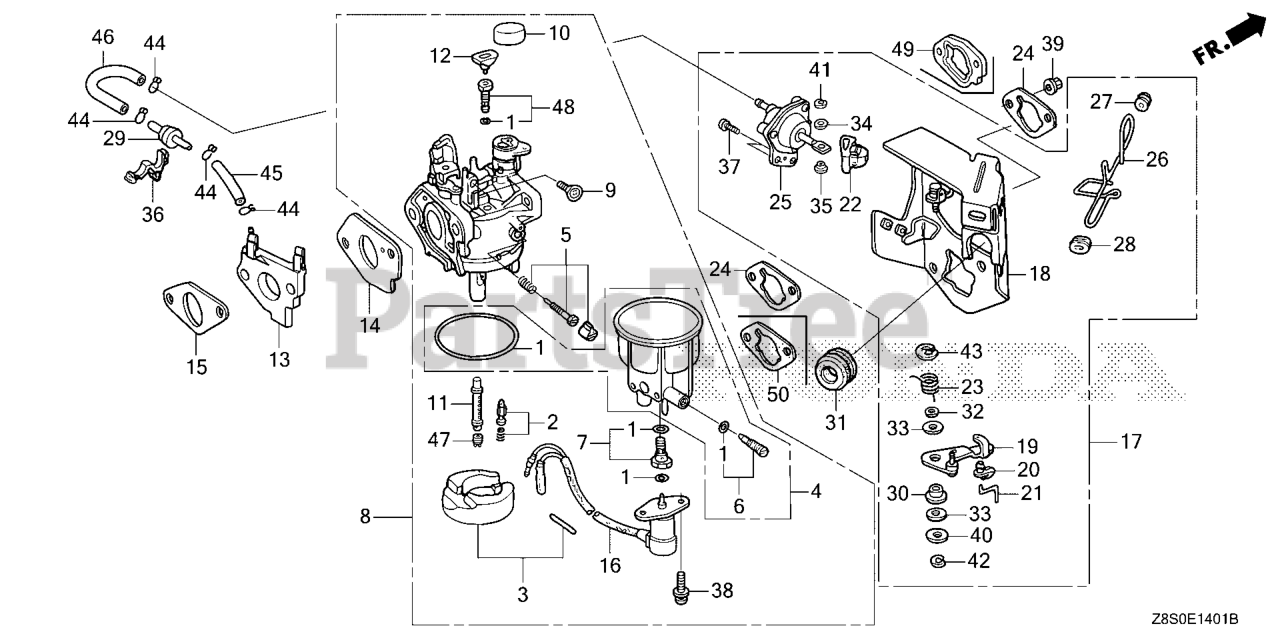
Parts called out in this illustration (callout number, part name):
1	GASKET SET
2	VALVE SET, FLOAT
3	FLOAT SET (CARBURETOR NO.)
4	CHAMBER SET, FLOAT
5	SCREW SET (CARBURETOR NO.)
6	SCREW SET, DRAIN (ADVENTURE GREEN) (CARBURETOR NO.)
8	CARBURETOR ASSY. (BE98L C)
9	SCREW, THROTTLE STOP
10	CAP, CHOKE LEVER DUST
11	NOZZLE, MAIN
12	COLLAR, SET
13	INSULATOR, CARBURETOR
14	GASKET, CARBURETOR
15	GASKET, INSULATOR
16	VALVE ASSY., SOLENOID
17	STAY ASSY., MANUAL CHOKE
18	STAY, SOLENOID
19	LEVER, CHOKE
20	JOINT, ROD
21	ROD, CHOKE
22	STOPPER, CHOKE ROD
23	SPRING, MANUAL CHOKE
25	DIAPHRAGM ASSY.
26	ROD, CHOKE CONTROL
27	GROMMET, CHOKE ROD
28	GUIDE, CHOKE ROD
29	VALVE, DASHPOT CHECK
30	BUSH, ARM PIVOT
31	GROMMET, FENDER
32	WASHER, CHOKE LEVER
33	SEAL, CHOKE LEVER
34	WASHER, THRUST (2.7X8)
35	COLLAR, LEVER
36	CLIP, WIRE HARNESS
37	SCREW, PAN (5X12)
38	SCREW-WASHER (5X12)
40	WASHER, PLAIN (5MM)
41	E-RING (2MM)
42	E-RING (4MM)
43	E-RING (7MM)
44	CLIP, TUBE (B7)
45	BULK HOSE, VACUUM (3.5X8000) (3.5X130)
46	BULK HOSE, VACUUM (3.5X8000) (3.5X130)
47	JET, MAIN (#82)
47	JET, MAIN (#85) Use up to Engine SN BE81B B.
47	JET, MAIN (#88) Use up to Engine SN BE81B B.
48	JET SET, PILOT (#45) (CARBURETOR NO.)
49	SPACER, CARBURETOR
50	GASKET, AIR CLEANER
